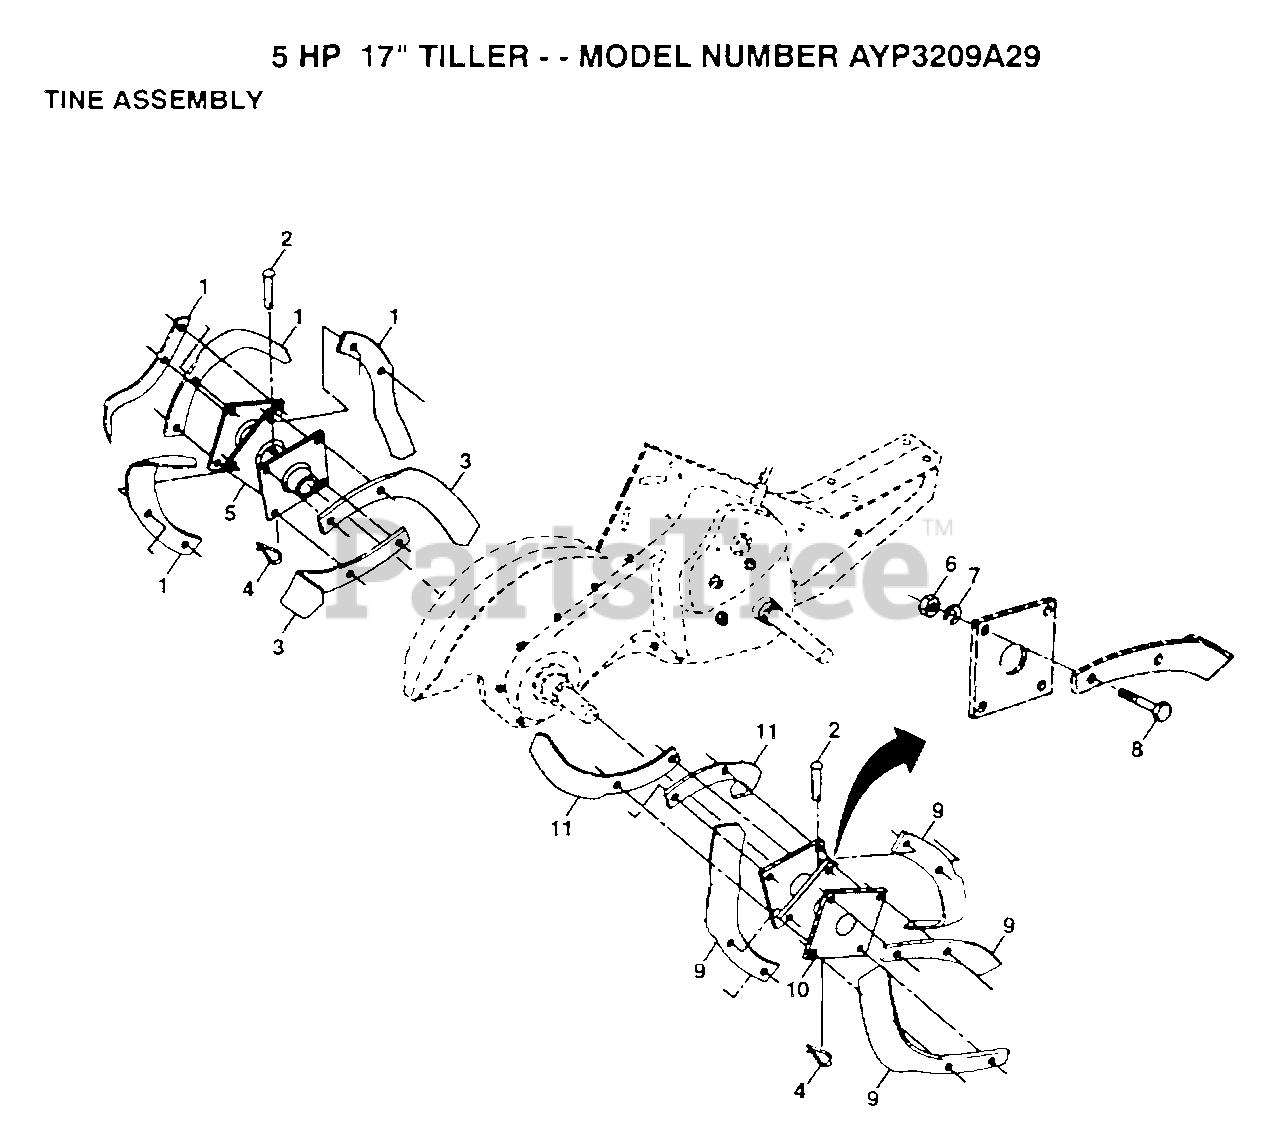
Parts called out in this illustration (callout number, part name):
2	PIN.CLEVIS.SHEAR
3	"TINE.LH.12"""
4	RETAINER.SPRING
5	HUB&PLATE ASM LH
7	LOCKWASHER
8	BOLT
10	HUB&PLATE ASM RH
11	"TINE.RH.12"""
